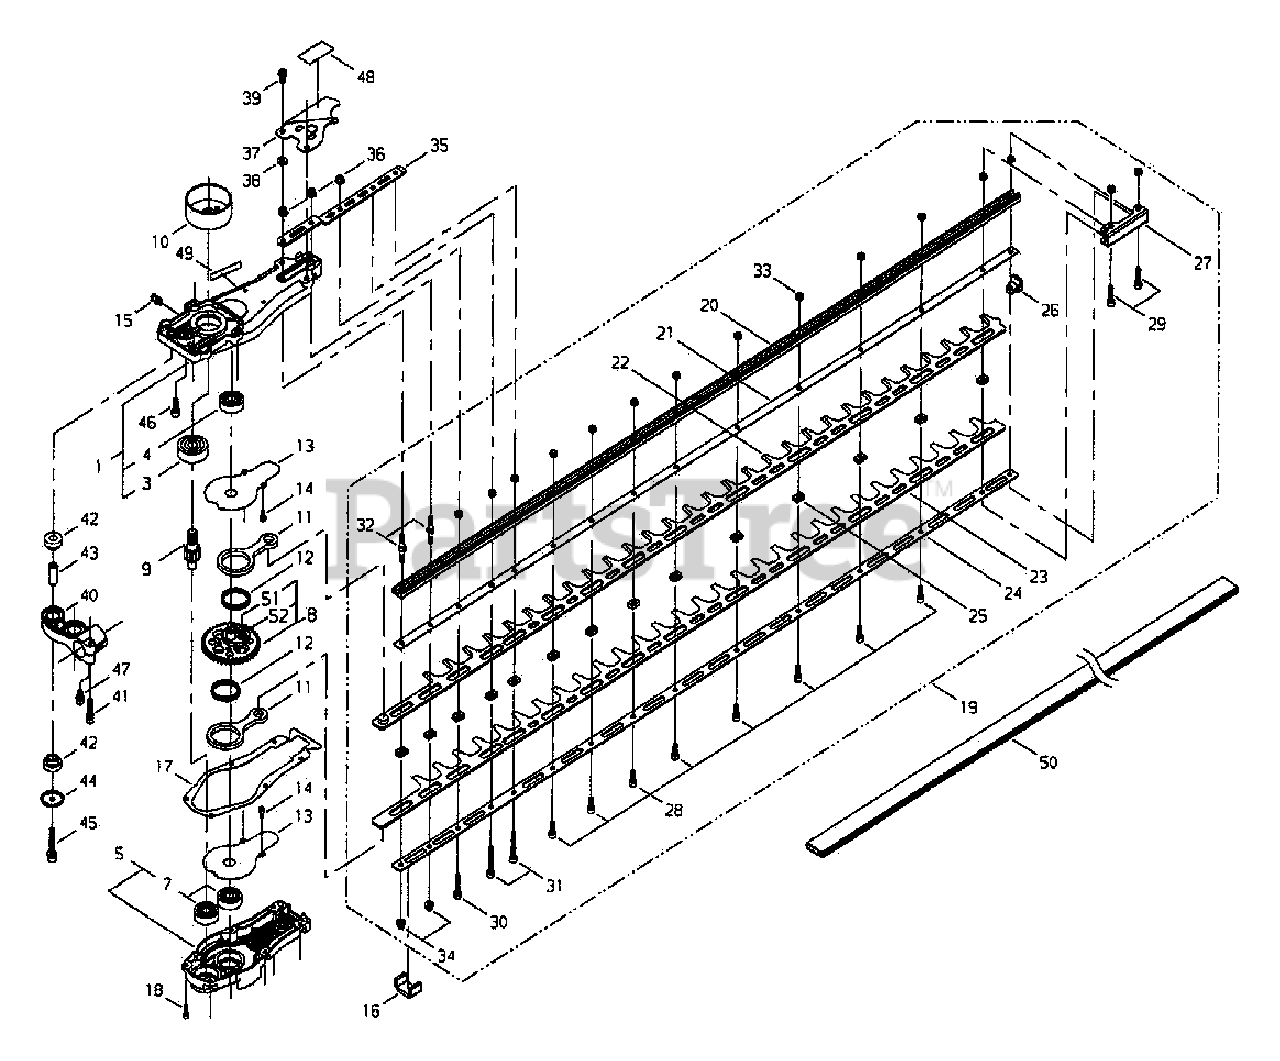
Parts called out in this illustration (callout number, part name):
1	GEAR CASE ASSY
3	BEARING, BALL - 6301DDU
4	BEARING, BALL - 6200ZZ
5	GEAR CASE COVER ASSY
7	BEARING, BALL - 6200ZZ
8	CAM GEAR ASSY
9	GEAR - PINION
10	DRUM, CLUTCH
11	ROD, CONNECTING
12	BEARING, NEEDLE - 30
13	PLATE, GEAR CASE
14	SCREW - 4X8
15	FITTING, GREASE
16	SEAL, FELT
17	GASKET, GEAR CASE
18	SCREW - 4X14
19	BLADE KIT - 40" (102cm)
20	SUPPORT, BLADE - 40" (101cm)
21	PLATE - UPPER
22	BLADE - 40" (101cm) -- UPPER
23	BLADE - 40" (101cm) -- LOWER
24	PLATE - LOWER
25	SPACER
26	BLOCK
27	PLATE, GUIDE
28	SCREW - 5X14
29	SCREW - 5X20
30	SCREW - 5X25
31	STUD - 5
32	SCREW - 5X35
33	LOCKNUT - 5
34	NUT - 5
35	PLATE, ANGLE
36	NUT - 5
37	PROTECTOR
38	WASHER - 5
39	SCREW - 6X12
40	MOUNT, HANDLE
41	SCREW - 5X25
42	CUSHION
43	COLLAR - 6
44	COVER, CUSHION
45	SCREW - 6X35
46	SCREW - 6X16
47	SCREW - 5X12
48	LABEL - WARNING
49	LABEL - LUBRICATION
50	COVER, BLADE - 40" (102cm)
51	GEAR - SPUR
52	CAM
